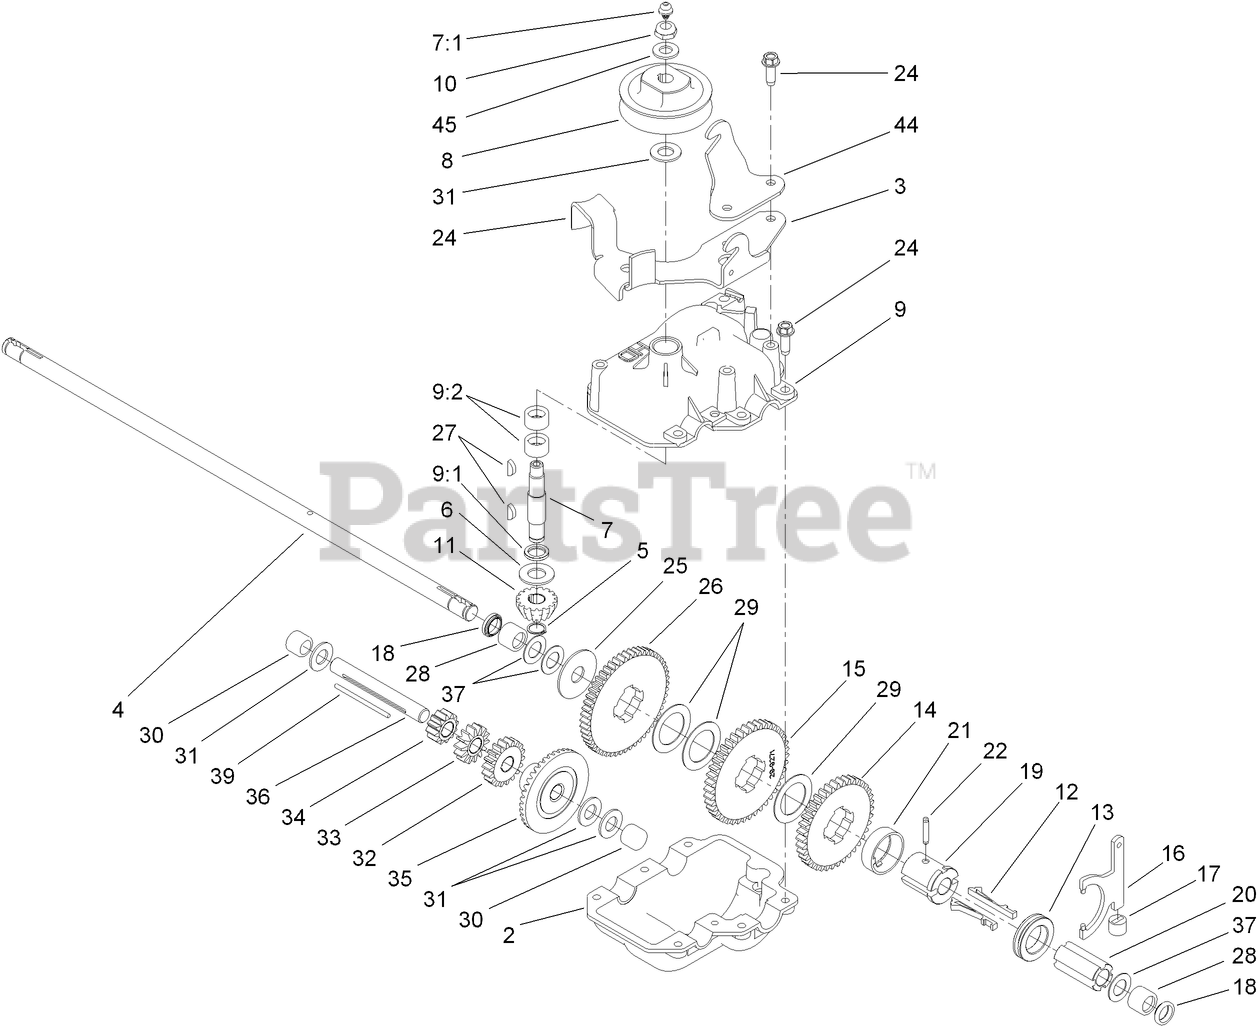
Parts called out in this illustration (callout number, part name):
2	GEARCASE-LOWER
3	BRACKET-GUIDE, BELT
4	SHAFT-OUTPUT
5	RING-RETAINING
6	WASHER-THRUST
7	INPUT SHAFT ASM
7:1	FITTING-GREASE, ZERK
8	PULLEY
9	UPPER GEARCASE ASM
9:2	BEARING-NEEDLE
10	NUT-HEX
11	PINION-BEVEL
12	KEY-SHIFT
13	COLLAR-SHIFT
14	GEAR-38T
15	GEAR-42T
16	YOKE-SHIFT
17	BUSHING-YOKE
18	SEAL-OIL
19	SLEEVE-GEAR
20	SLEEVE
21	RETAINER-KEY
22	PIN-GROOVE
24	SCREW-HWHTF
25	WASHER
27	KEY-WOODRUFF
28	BEARING-CAGED NEEDLE ROLLER
29	WASHER
30	BEARING-NEEDLE, CLOSED
31	WASHER-THRUST
32	GEAR-18T
33	GEAR-14T
34	GEAR-12T
35	GEAR-BEVEL
36	SHAFT-INTERMEDIATE
37	WASHER-PLAIN
44	BRACKET-ENGAGE, TRACTION
45	WASHER-FLAT
